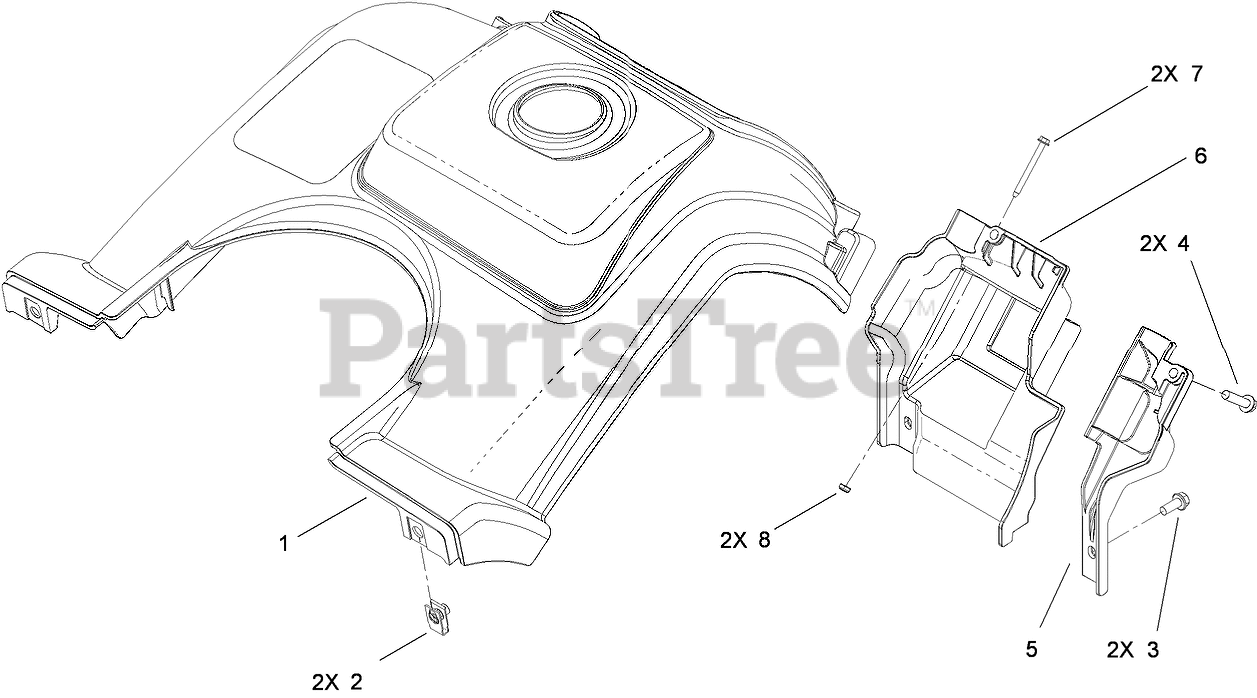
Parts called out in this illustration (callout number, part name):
1	SHROUD ASM
3	SCREW-HWH
4	SCREW-PLASTIC
5	SHROUD-LOWER, LH
6	SHROUD-LOWER, RH
7	SCREW-HWH
8	NUT-HEX
